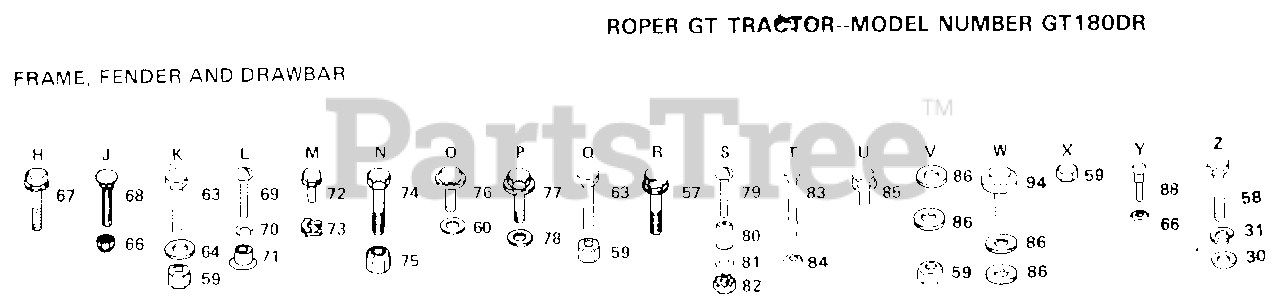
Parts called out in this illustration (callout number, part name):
30	WASHER
31	LOCKWASHER
57	SCREW
60	WASHER PM
63	BOLT
64	WASHER
68	BOLT
69	SCREW
70	LOCKWASHER
71	WELDNUT
73	"""J"" FASTENER LT"
74	BOLT T
76	SCREW HEX CRT
77	SCREW
78	WASHER M
79	SCREW
80	SPACER LT
81	WASHER
83	BOLT
84	NUT GTV
85	SCREW LT
86	WASHER
94	SCREW GTV
